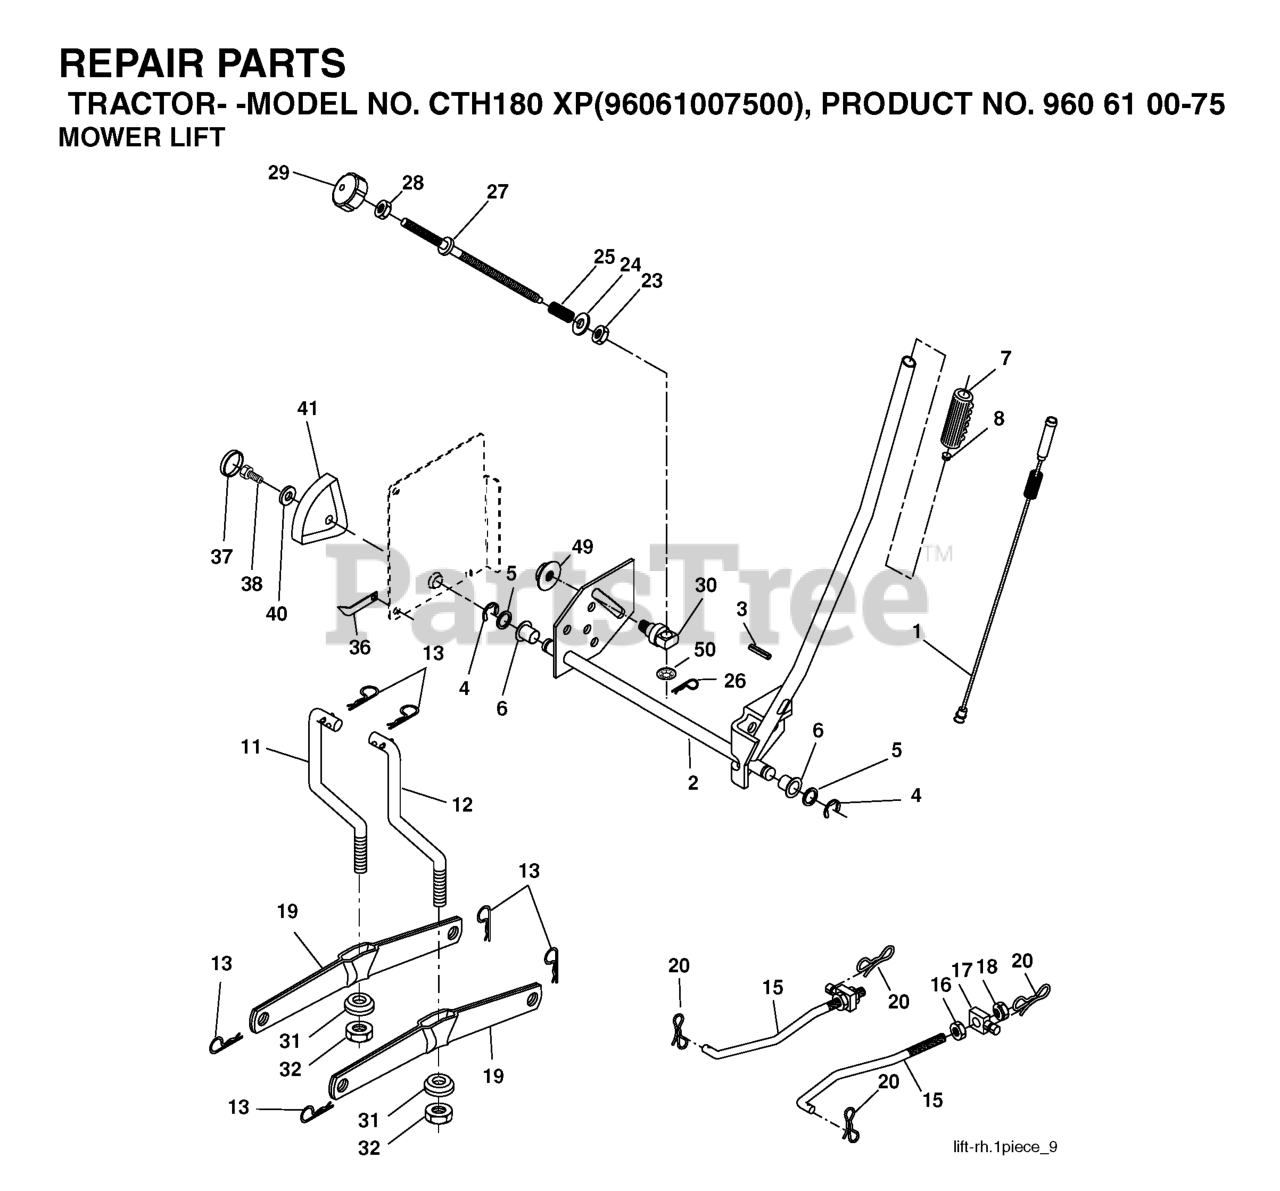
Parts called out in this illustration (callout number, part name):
1	WIRE ASM INNER W/ PLUNGER LT
2	SHAFT ASM R HANDLE
3	PIN GROOVE.
4	RETAINING RING LT
6	BEARING.NYLON
7	GRIP HANDLE
8	PLUNGER BUT KIT
11	LINK
12	LINK
13	RETAINER-SPRNG RB
15	LINK.SUSPENSION.FRONT
16	NUT.HEX.JAM.1/2-13
18	NUT.LK.W/WSH.1/2.
19	ARM.REAR.SUSPENSION
20	PIN.COTTER.7/16.BOW TI.
25	SPRING**
26	RETAINER CLIP
27	ROD ADJ LIFT
28	NUT
29	KNOB INF 3/8-16
31	BEARING.PIVOT.LIFT
32	NUT CROWNLOCK 3/8-24
36	POINTER, HEIGHT INDICATOR(2 2)
38	SCREW 5/16-18X1
41	HEIGHT INDICATOR
49	NUT
50	NUT PUSH M
